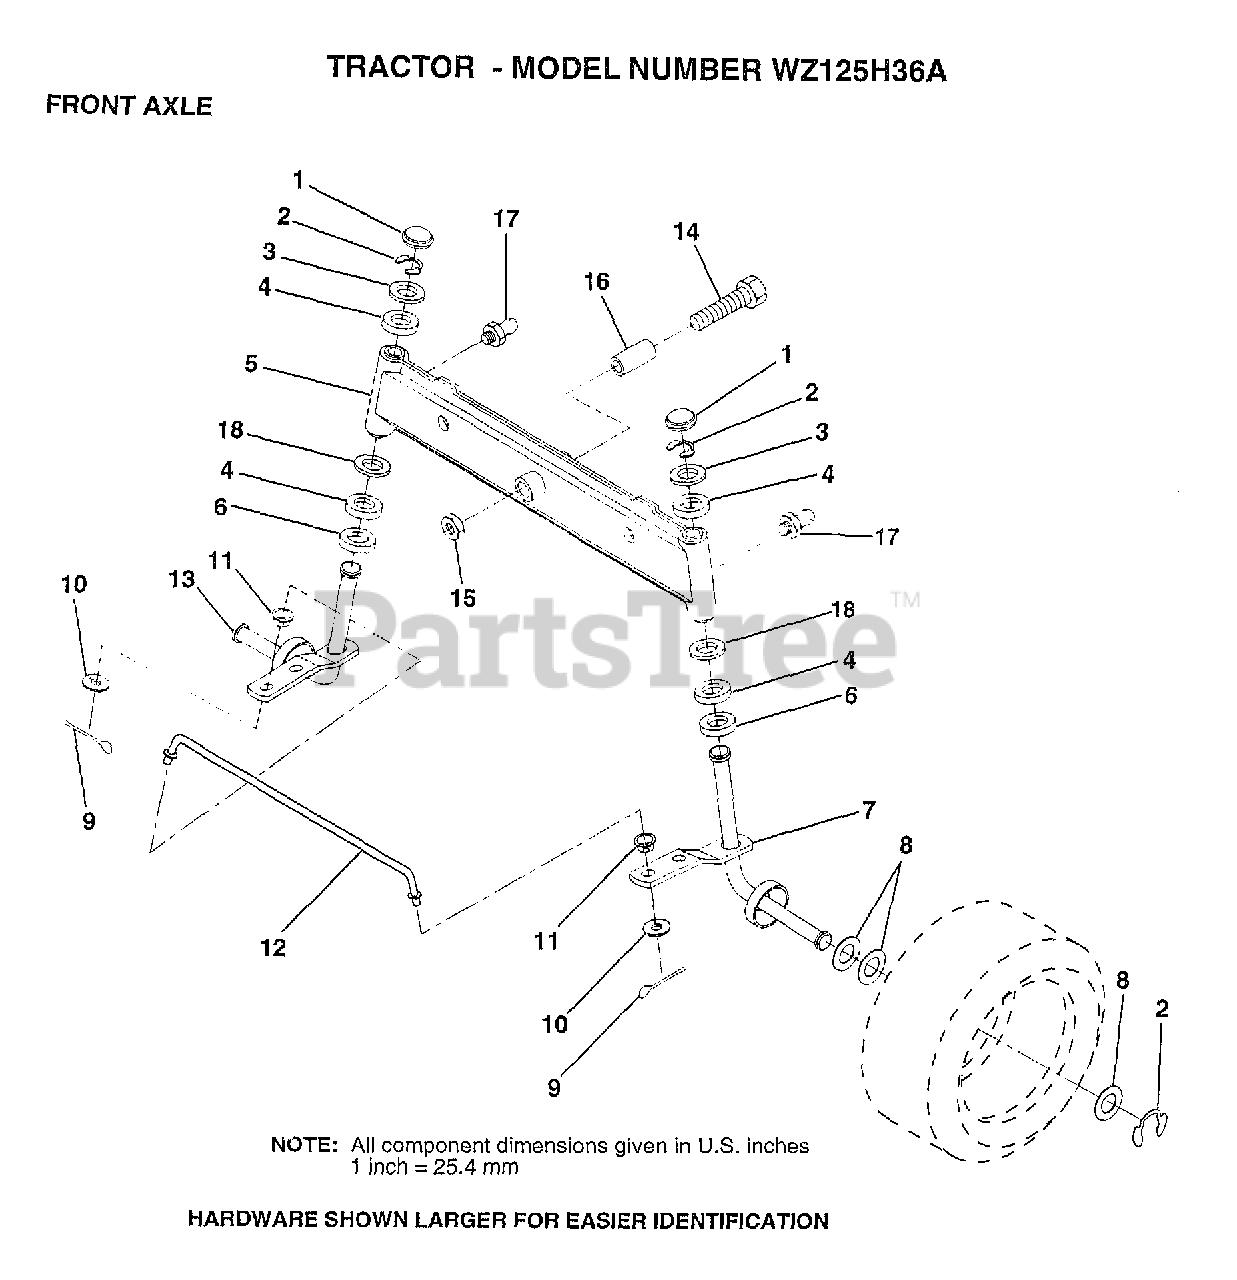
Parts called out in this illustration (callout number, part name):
1	CAP
2	RING
3	WASHER
4	COL. SRTG. BEAR.
5	AXLE ASM FRONT
6	WASHER .T
7	SPINDLE.ASSY.RH
8	WASHER
9	COTTER PIN
10	WASHER
11	BUSHING.DRAGLINK
12	TIE ROD
13	SPINDLE.ASSY.LH
14	BOLT HEX 5/8-11
15	"NUT-LOC,FLANGE LT"
16	BEARING
17	ZERK M
18	WASHER
